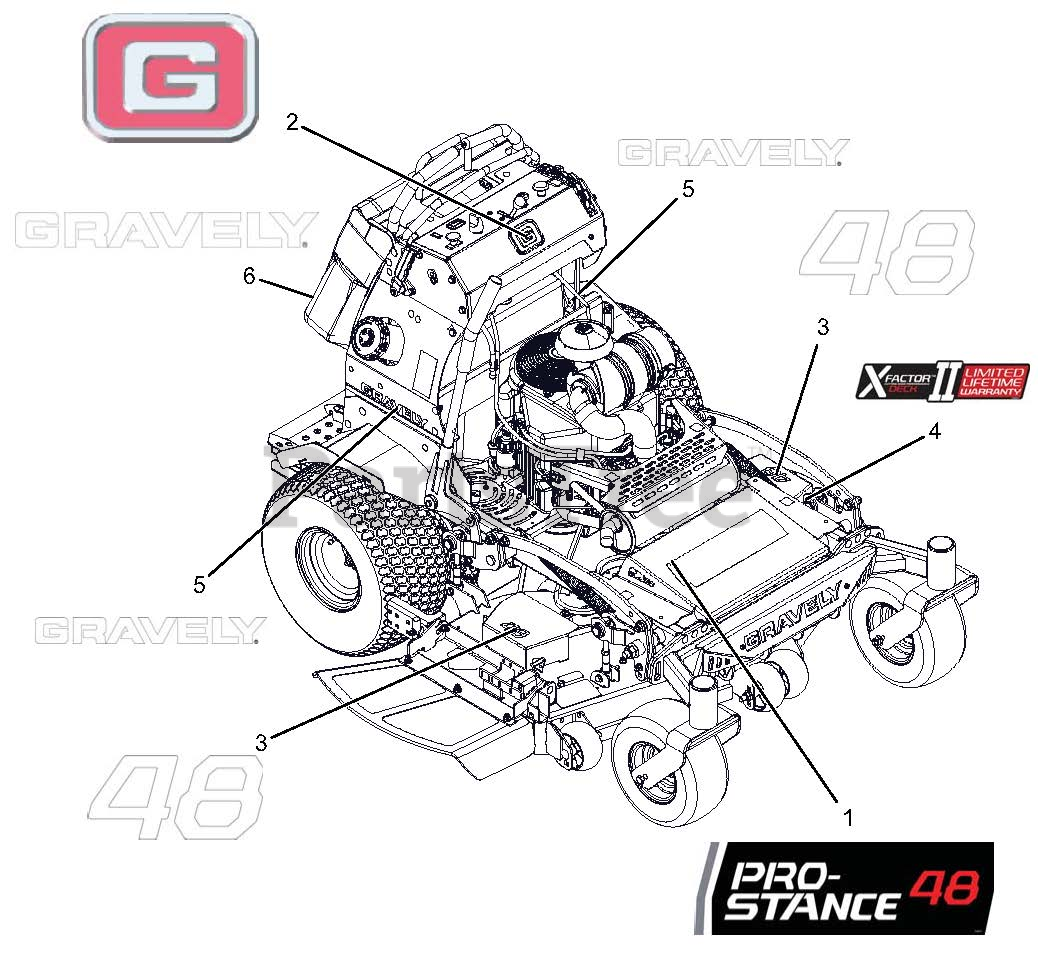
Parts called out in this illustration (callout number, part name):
1	DECAL, PROSTANCE 48
2	DECAL, GRAVELY BRAND
3	DECAL, 48"
4	DECAL, X-FACTOR DECK
5	DECAL, 9.5" GRAVELY LOGO
6	DECAL, 13.5" GRAVELY LOGO
